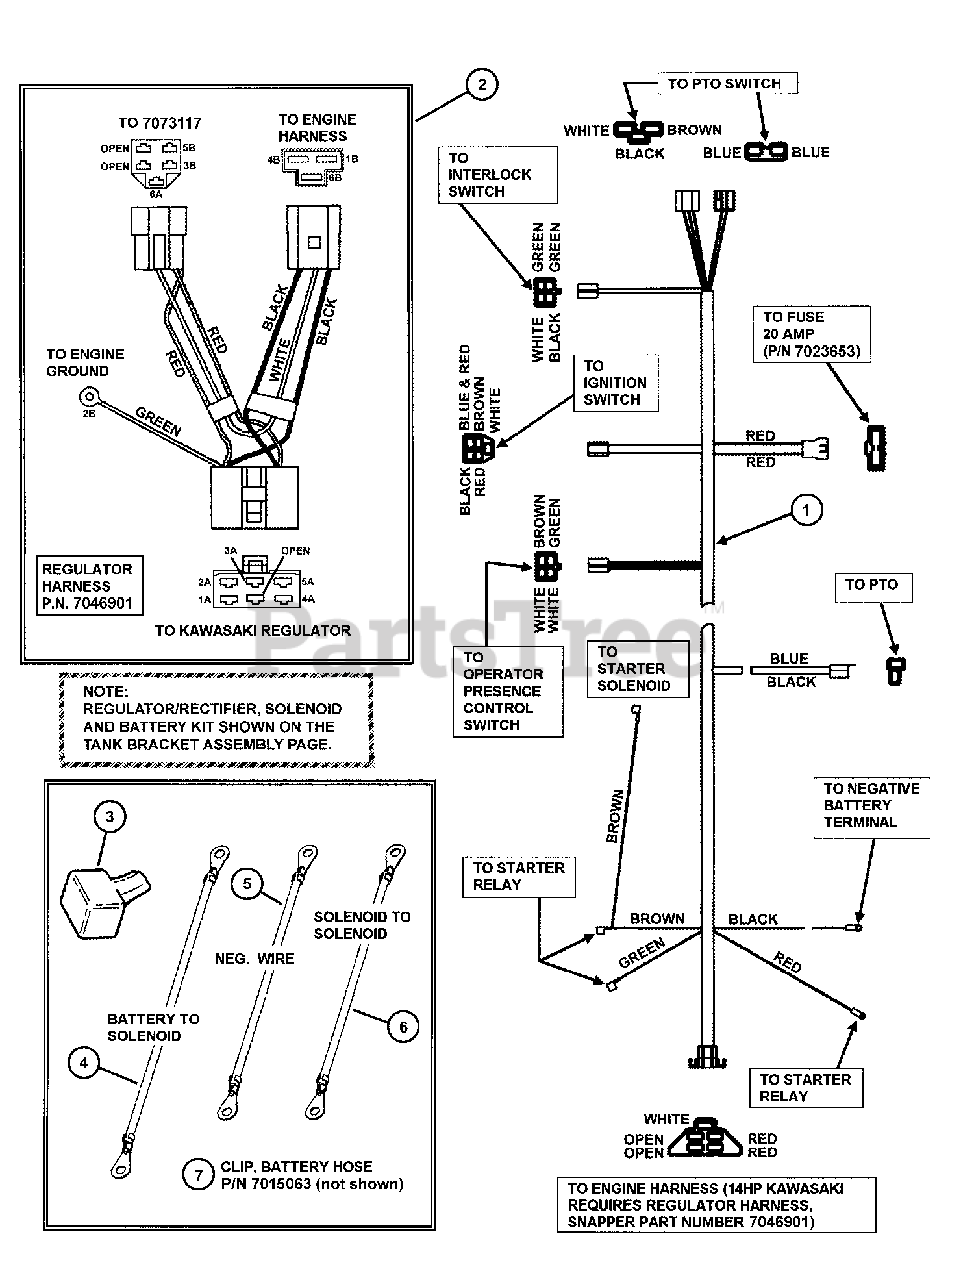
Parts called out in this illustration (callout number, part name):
1	WIRING HARNESS
2	HARNESS, Regulator, Kawasaki
3	COVER, Battery Cover
4	WIRE, Solenoid to Battery
5	WIRE, Negative
6	WIRE, Positive
